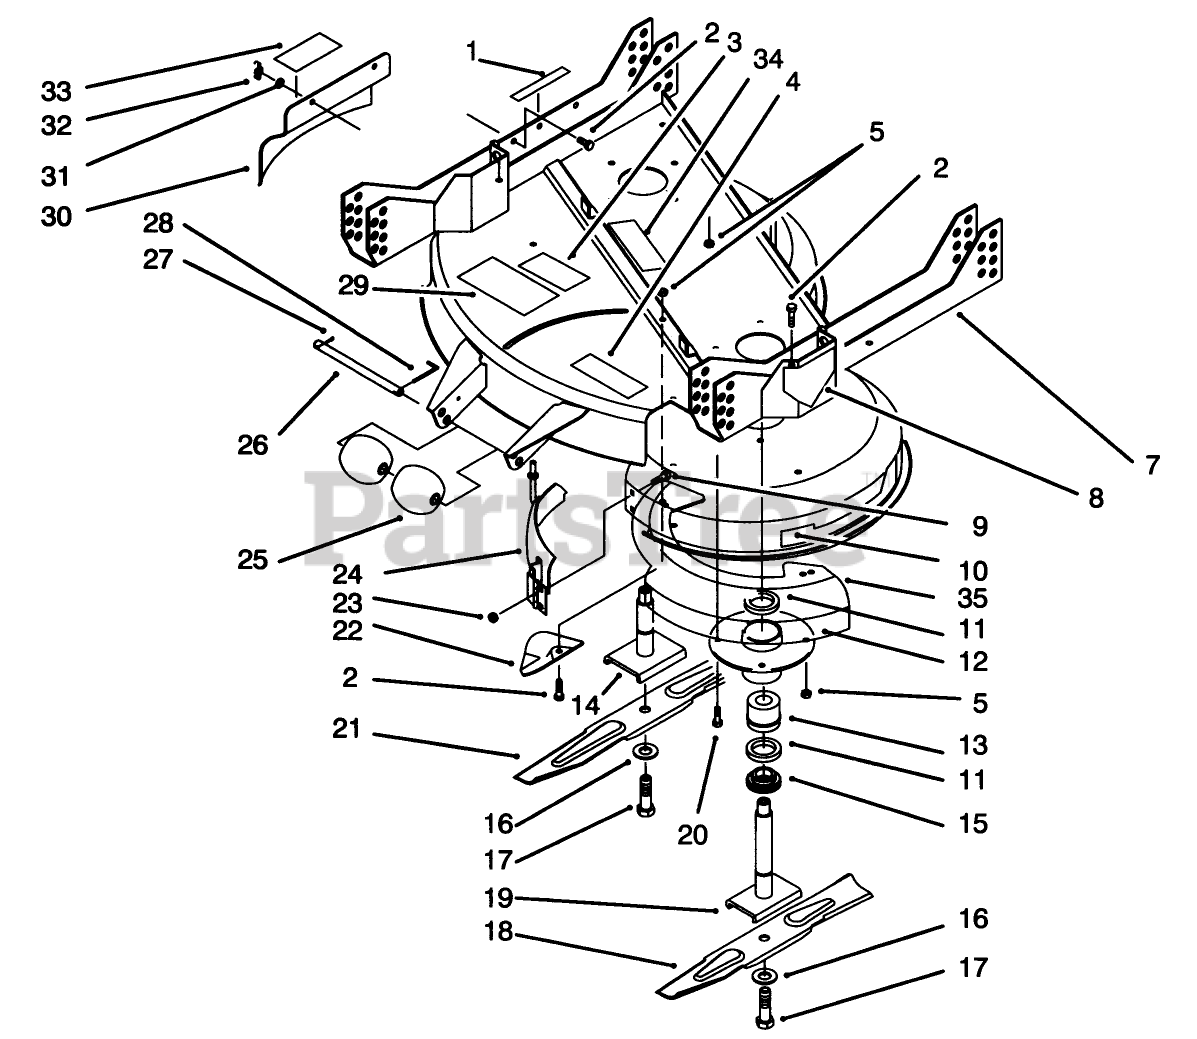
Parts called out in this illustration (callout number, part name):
1	DECAL-DANGER, DEFLECTOR
2	SCREW-HH
3	DECAL-TORQUE
4	DECAL - DISCHARGE DOOR
5	NUT-LOCK, NI
7	Deck Support (Incl. Ref. #3, 4, 6, 8, & 29)
8	DECAL-DANGER
9	SCREW-CARRIAGE
10	DECAL - 37"
11	SEAL-OIL
12	SPINDLE HOUSING
13	BEARING ASM
14	SHAFT-SPINDLE
15	SPACER
16	WASHER-LOCK
17	SCREW-BLADE
18	Blade
19	SHAFT-SPINDLE
20	SCREW-HH
21	Blade
22	PLATE-KICKER
23	NUT-KEPS
24	Cover-Front
25	ROLLER
26	SHAFT-ROLLER
27	PIN-COTTER
28	PIN-SPECIAL
29	DECAL-DANGER, THROWN OBJECT
30	Cover-Discharge
31	WASHER-LOCK
32	NUT-WING
33	DECAL - DANGER
34	DECAL-DANGER
35	Insert-Deck
